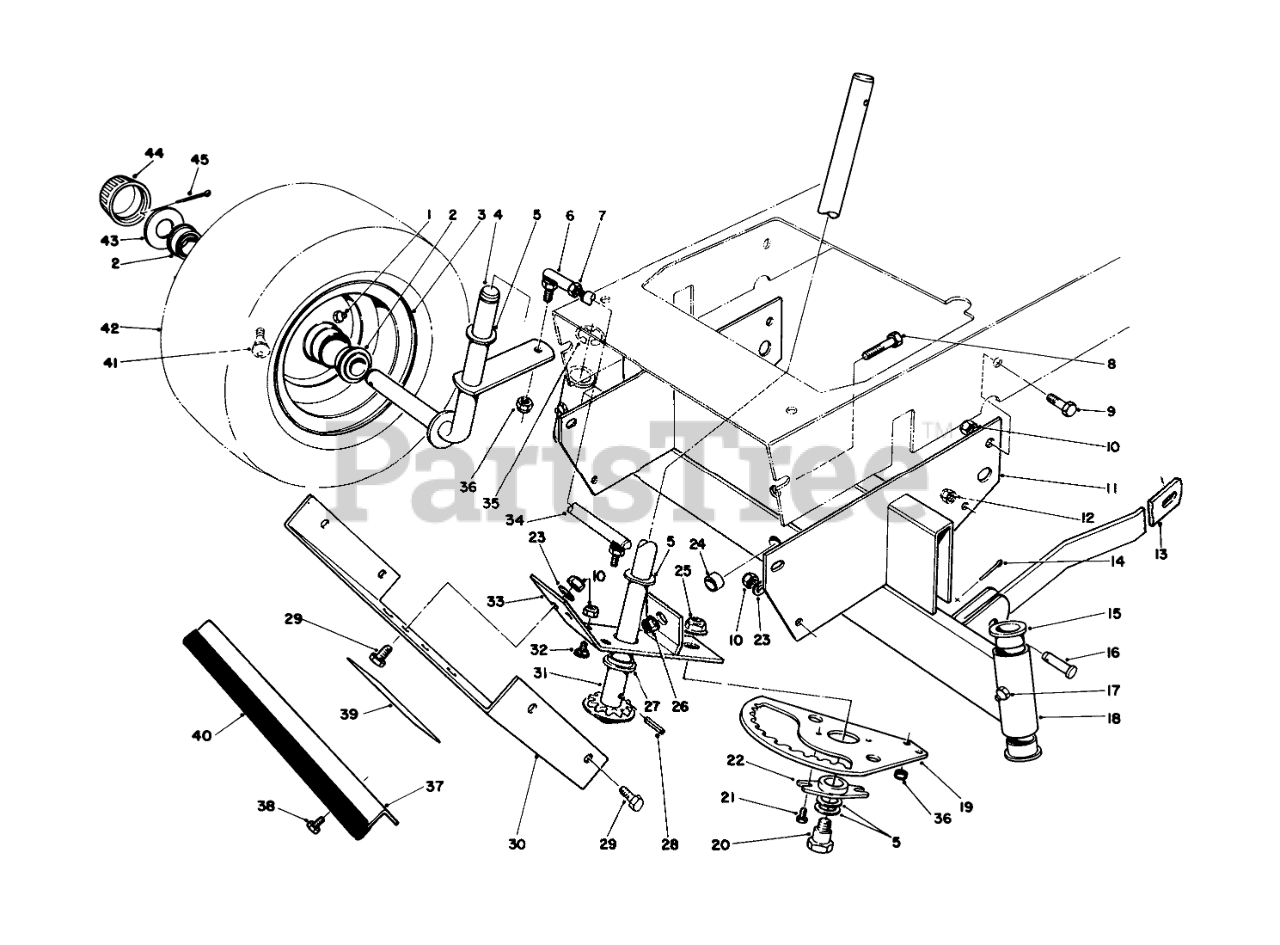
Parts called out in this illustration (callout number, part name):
1	FITTING-GREASE
2	Bearing
4	Spindle RH
5	WASHER-THRUST
6	JOINT-BALL
7	NUT-JAM
8	SCREW-HH
9	SCREW-HH
10	NUT-LOCK, NI
11	Support
12	NUT-LOCK, CONE
13	Arm-Suspension, Front
14	PIN-COTTER
15	BEARING-FLANGE
16	PIN-CLEVIS
17	GREASE FITTING
18	Axle-Front (Incl. Ref. #15 & 17)
19	STEERING RACK B
21	SCREW
22	BUSHING-SECTOR
23	WASHER-PLAIN
24	SPACER-AXLE, FRONT
25	NUT-HF
26	NUT-HF
27	BEARING-FLANGE
28	PIN-ROLL, SLOTTED
29	SCREW-HH
30	Cover-Front
31	STRG SHAFT WA
32	SCREW-CARR
33	Bracket-Steering Rack (Incl. Ref. #27)
34	Tie Rod-Steering (Incl. Ref. #35 & 36)
35	E-RING
36	NUT-LOCK
37	FRONT GUARD R
38	SCREW-HWHTF
39	Decal-Warning
40	TRIM-FRONT GUARD
41	STEM-VALVE
42	TIRE,PNEU.11X4.00X5
43	WASHER-PLAIN
44	CAP-HUB
45	PIN-COTTER
